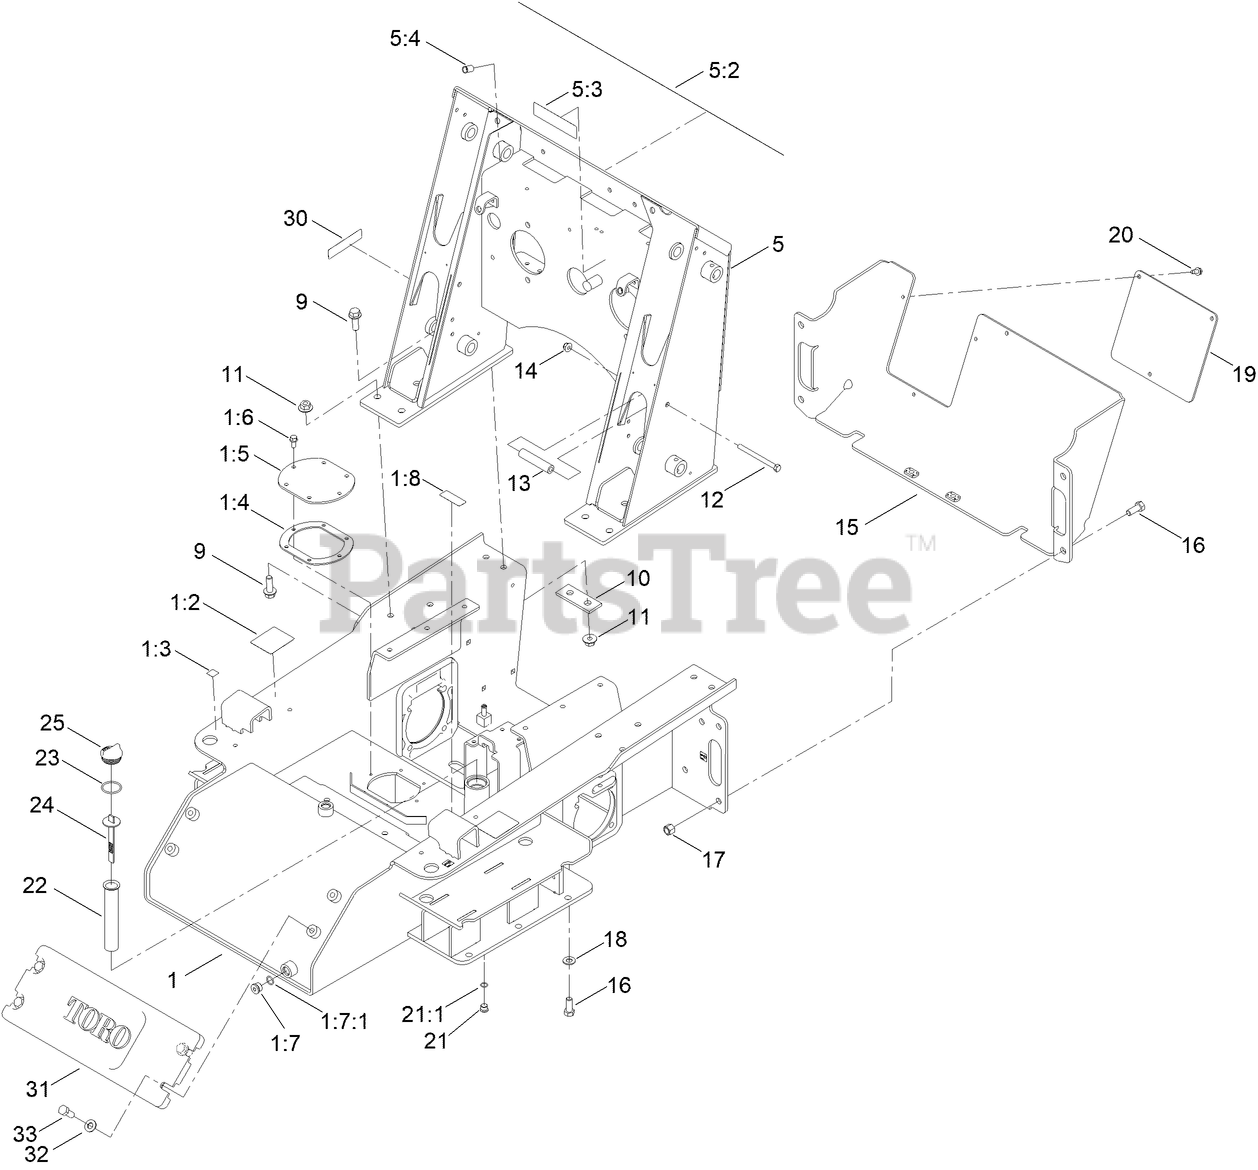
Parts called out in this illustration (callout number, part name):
1	CHASSIS ASM
1:2	DECAL-WARNING
1:3	DECAL-POINT, LIFT
1:4	GASKET-COVER, ACCESS
1:5	COVER-TANK
1:6	SCREW-HHF
1:7	PLUG-HEX
1:7:1	O-RING
1:8	DECAL-OIL, HYD
5	LOADER TOWER ASM
5:2	DECAL-PANEL, CONTROL
5:3	DECAL-DANGER
5:4	NUT-CLINCH
9	SCREW-HHF
10	PLATE-STIFFENER
11	NUT-LOCK, FLANGE
12	SCREW-HH
13	TUBE-SPACER
14	NUT-HF, NI
15	COVER-REAR
16	SCREW-HH
17	NUT-LOCK, NI
18	WASHER-FLAT
19	PANEL-REAR
20	SCREW-THD ROLL, HWH
21	PLUG-HEX, HOLLOW
21:1	O-RING
22	FILTER-SCREEN
23	O-RING
24	DIPSTICK-OIL
25	PLUG-PLASTIC
30	DECAL-ARRESTOR, SPARK
31	COUNTERWEIGHT-FRONT
32	WASHER-FLAT
33	SCREW-HH
